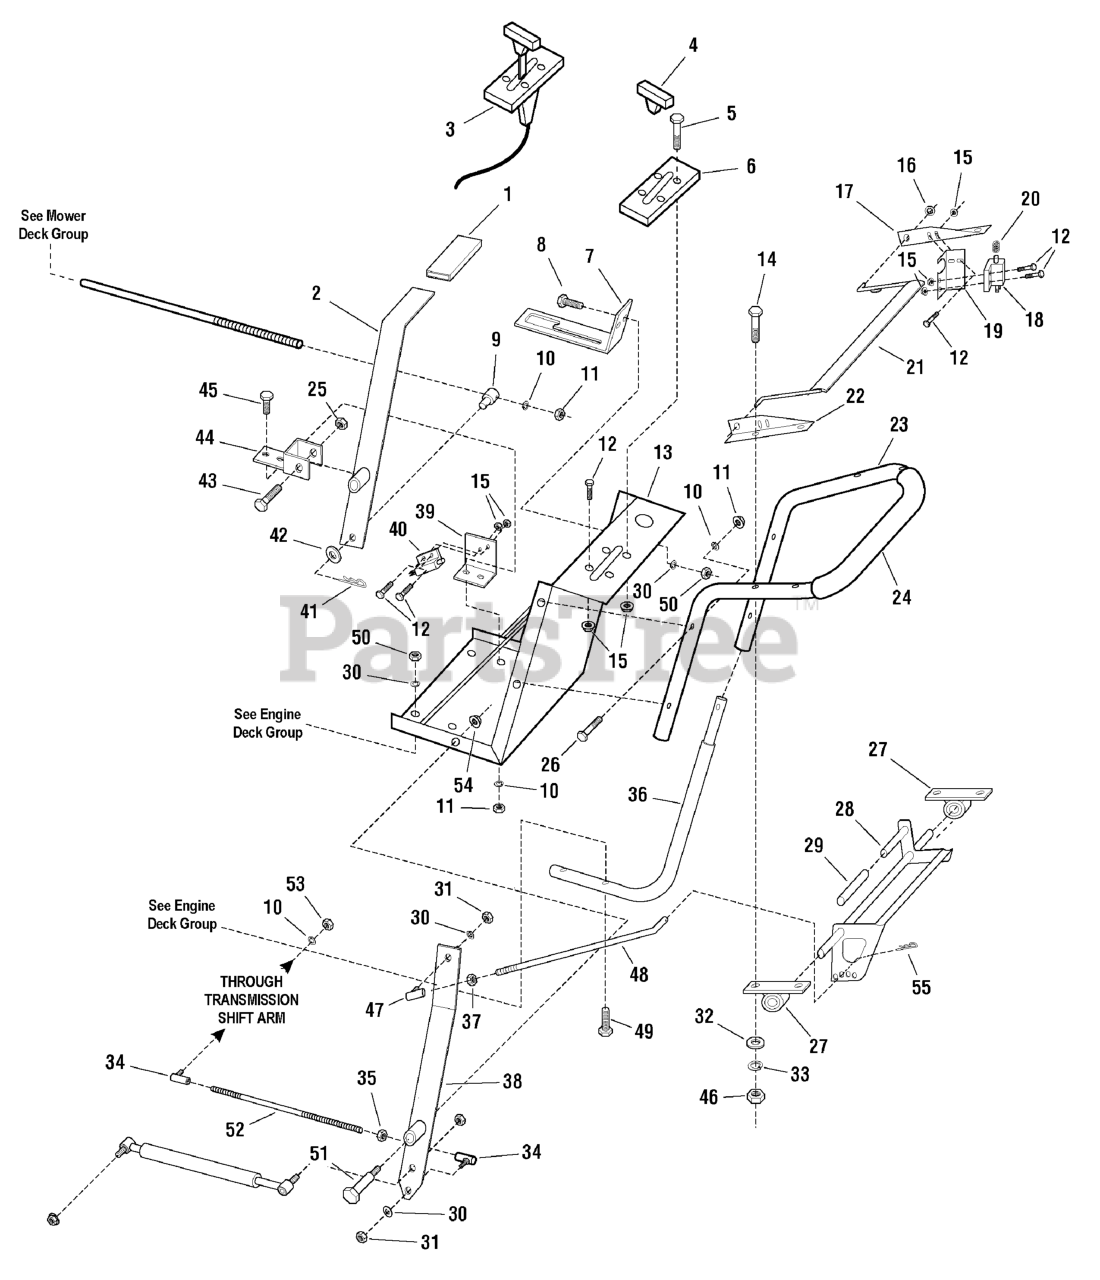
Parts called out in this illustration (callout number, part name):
1	HANDLE GRIP
2	Blade Clutch Engagement Lever
3	Throttle Control Cable Assembly, 13 HP Honda
3	Throttle Control Cable Assembly, 15 HP Kawasaki
3	Throttle Control Cable Assembly, 9 HP Briggs
4	Throttle Control, T-Handle
5	Rivet, 3/16
6	Throttle Speed Indicator Plate
7	Blade Engage Lever Lock Bracket
8	BOLT, 3/8-16 x 1
9	Rod, Fitting End
10	Lockwasher, 5/16
11	NUT, Hex, 5/16-18
12	Screw, 8-32 x 3/4
13	Control Deck & Dash Panel
14	BOLT, 1/4-20 x 1-3/4
15	NUT Assembly, 8-32
16	Push Nut, 5/16
17	Safety Bar Pivot Bracket, Left
18	Safety Switch
19	Safety Switch Mounting Bracket
20	Safety switch return spring
21	Safety Bar
22	Safety Bar Pivot Bracket, Right
23	Upper Handle
24	Foam Handle Cover
25	NUT, Hex Flangelock, 1/2-13
26	BOLT, 5/16-18 x 1-1/2
27	Bearing, 3/4 ID
28	Drive Engagement Bar
29	Handle, Grip, Reverse
30	Lockwasher, 3/8
31	NUT, Jam, 3/8-24
32	Flatwasher, 1/4
33	Lockwasher, 1/4
34	Ball Joint, 5/16-24
35	NUT, Hex Jam, 3/8-24, LH
36	Lower Handle
37	NUT, Jam, 3/8-24
38	Transmission Drive Intermediate Lever
39	Deck Safety Switch Bracket
40	Deck Safety Switch
41	Bridge Pin, #2
42	Flatwasher, 3/8
43	BOLT, 1/2 x 2-1/2
44	Blade Clutch Engagement Lever Bracket
45	BOLT, 5/16-18 x 1
46	NUT, Hex, 1/4-20
47	Ball Joint, 3/8-24 RH
48	Transmission Engagement Rod, Upper
49	BOLT, 5/16-18 x 1-3/4
50	NUT, Hex, 3/8-16
51	Bolt, Shoulder, 1/2 x 1 -3/8 to 3/8-16
52	Transmission Engagement Rod, Lower
53	NUT, Hex Jam, 5/16-24
54	NUT, Hex Centerlock, 3/8-16
55	Clip, Hair Pin
